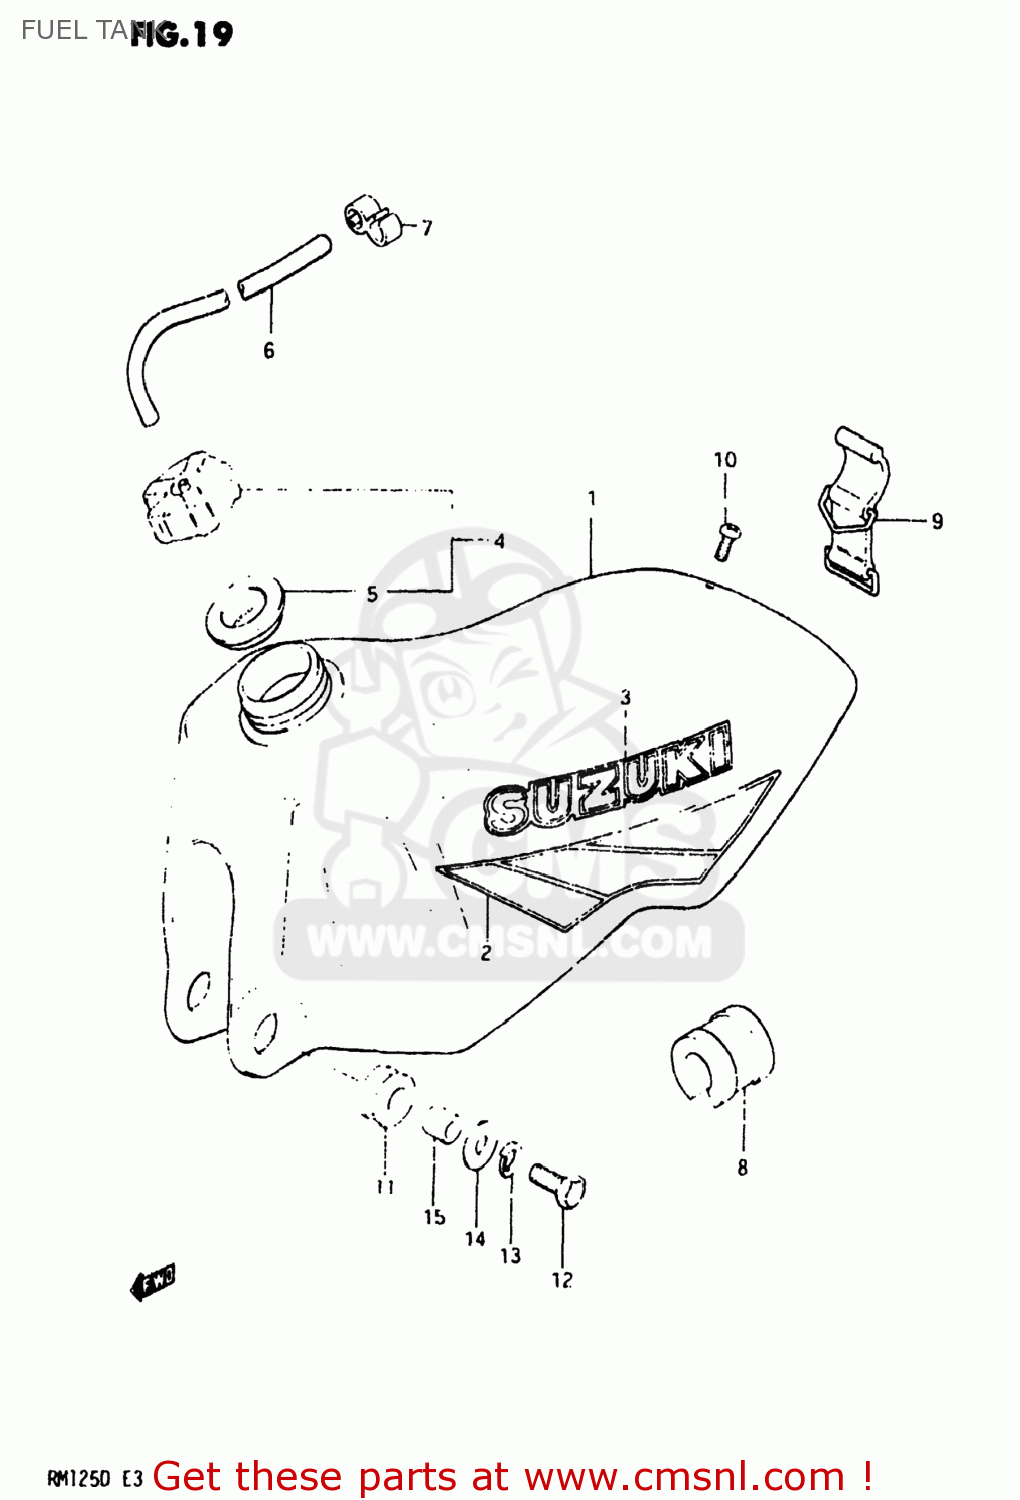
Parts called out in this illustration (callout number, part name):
1	TANK ASSEMBLY,FUEL
2	TAPE SET,FUEL TANK
3	EMBLEM
4	CAP SET,FUEL TANK
5	GASKET,FUEL TANK CAP (NAS)
6	HOSE
7	CLAMP,BREATHER HOSE
8	CUSHION,FUEL TANK UPR
9	BAND
10	SCREW (6X15)
11	CUSHION
12	BOLT (8X30)
13	LOCK WASHER
14	WASHER (8.5X26X1.2)
15	SPACER (8.8X12X13.5)
